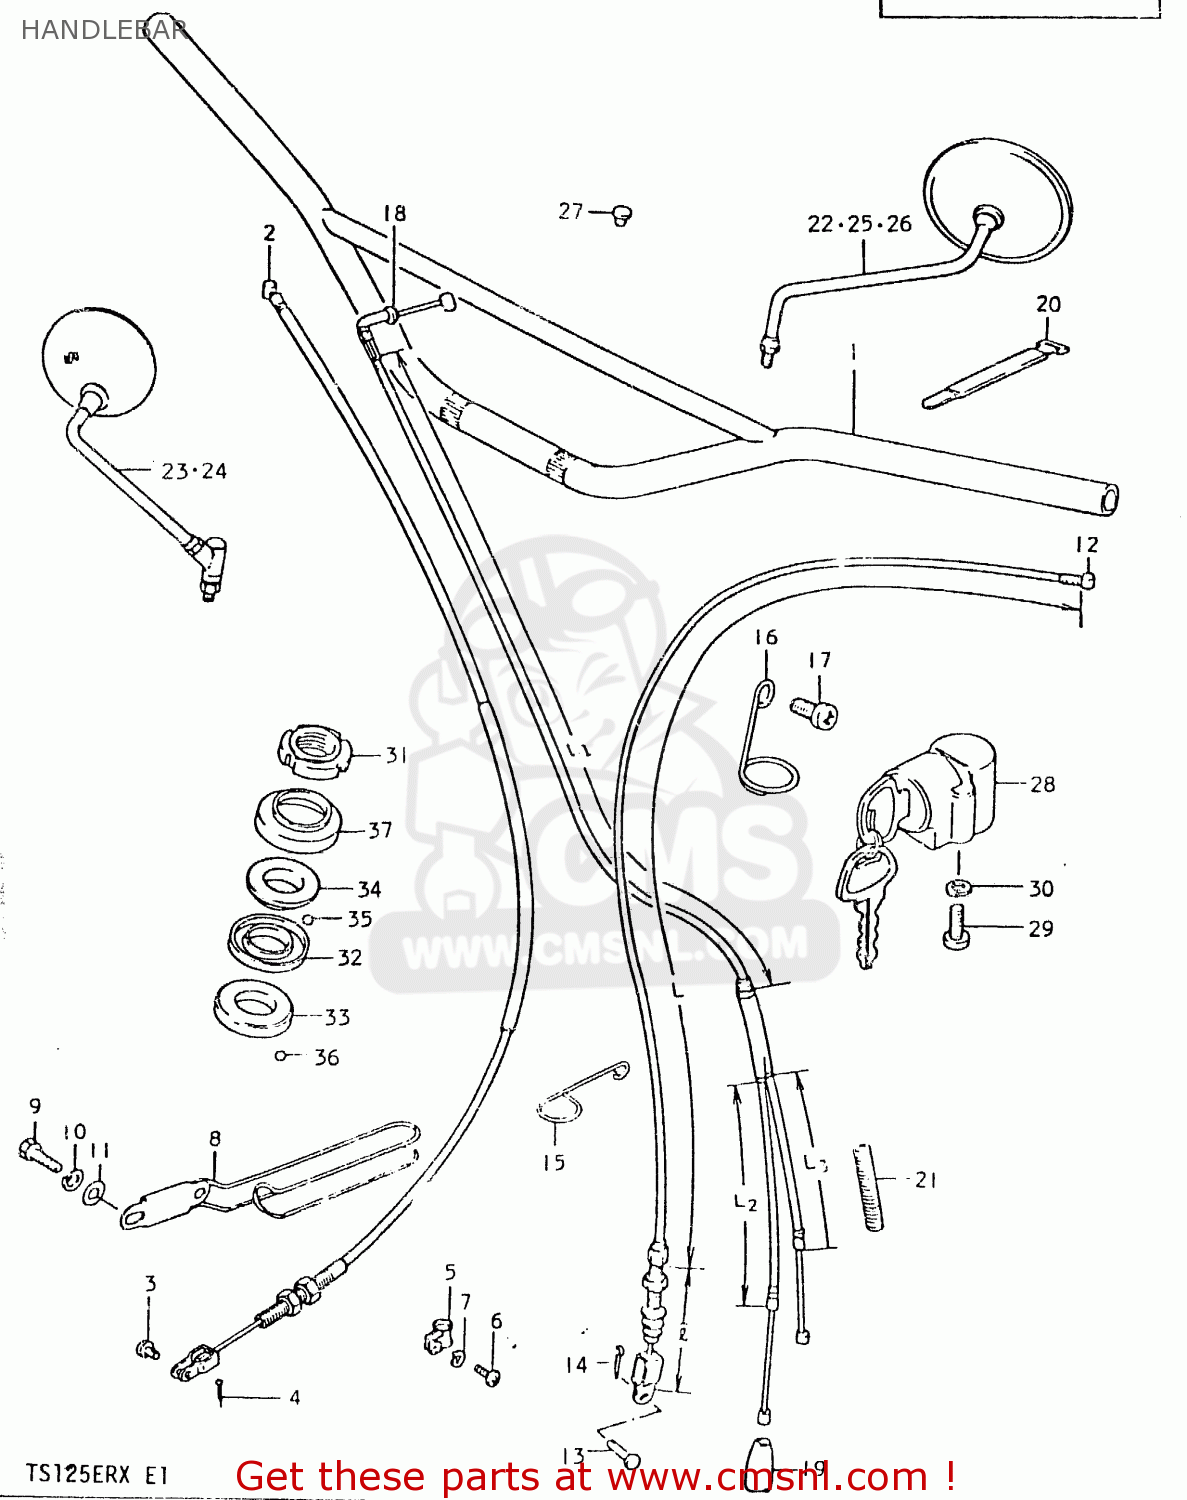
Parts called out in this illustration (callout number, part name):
1	HANDLEBAR
2	CABLE,FR BRAKE
3	PIN(L:13.5)
4	PIN
5	GUIDE,CABLE
6	SCREW
7	LOCK WASHER
8	GUIDE,CABLE
9	BOLT 8X12
10	LOCK WASHER
11	WASHER
12	CABLE ASSEMBLY,CLUTCH
13	PIN(L:15)
14	PIN
15	CLAMP
16	CLIP
17	SCREW
18	CABLE ASSEMBLY,THROTTLE
19	SEAL,DUST(7X18X30)
20	CLAMP
21	PROTECTOR,CABLE
22	MIRROR ASSEMBLY,LEFT
23	MIRROR ASSY,RH
24	MIRROR ASSY, REAR VIEW
25	MIRROR ASSY,LH
26	MIRROR ASSEMBLY,LEFT
27	CAP(OD:14)
28	LOCK ASSEMBLY,STEERING
29	SCREW
30	LOCK WASHER
31	NUT,STEERING STEM(25X44X10)
32	RACE,STEERING INNER UPR
33	LACE,STEERING INNER LWR
34	RACE,STEERING OUTER UPR
35	BALL
36	BALL
37	DUST SEAL,STEERING UPR
